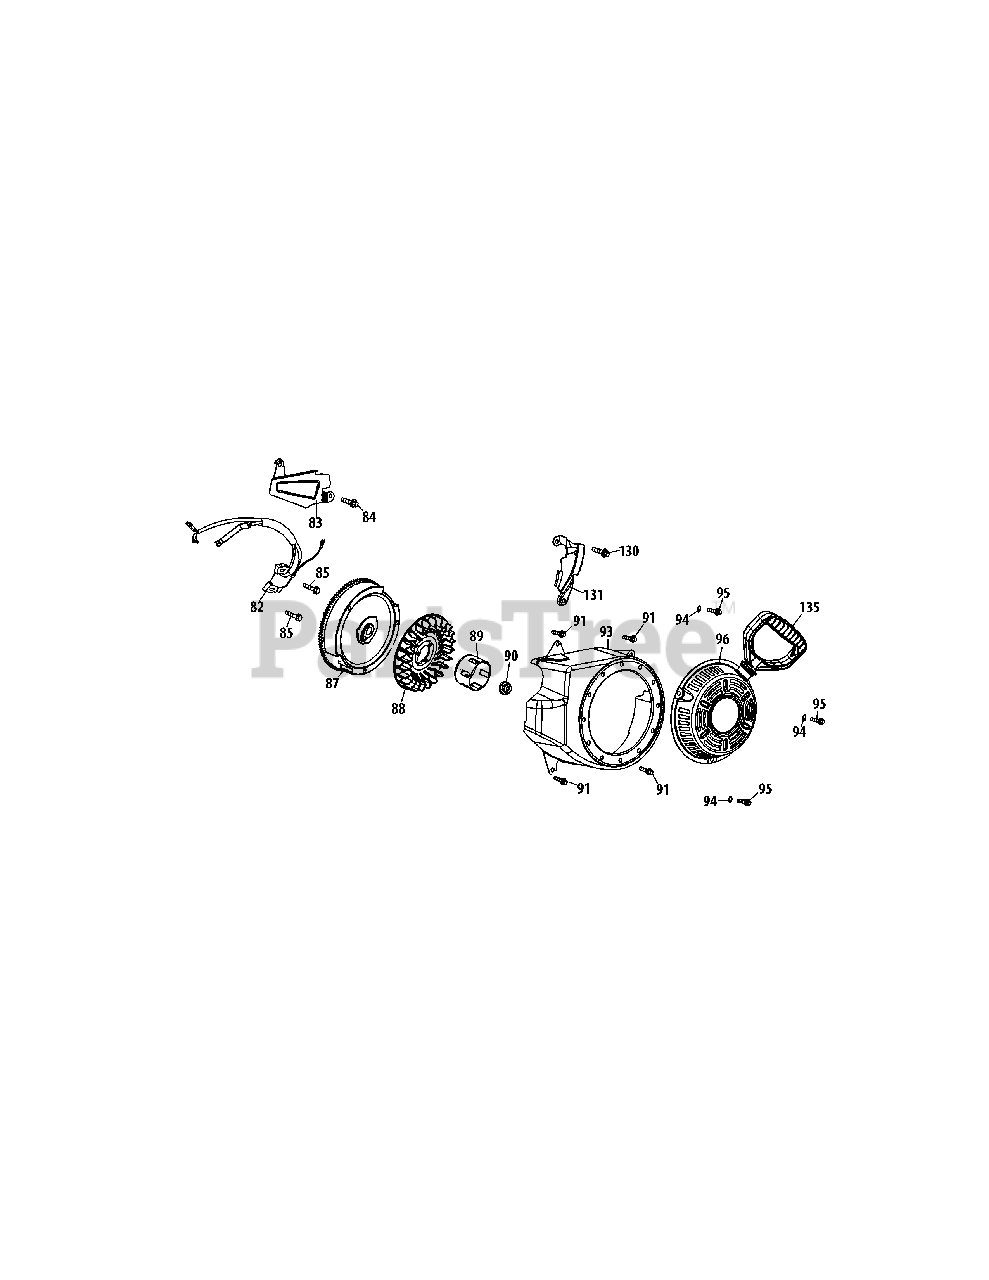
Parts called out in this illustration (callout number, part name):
82	Ignition Coil Assembly
83	Air Flow Shield
84	Bolt M6×10
85	Bolt M6×25
87	Flywheel
88	Fan, Cooling
89	Pulley, Starter
90	Nut, Special, M14×1.5
91	Bolt M6×12
93	Blower Housing
94	Gasket 6
95	Bolt M6×10
96	Recoil Starter
130	Bolt M6×18
131	Blower Housing Shield
135	Recoil Starter Handle
